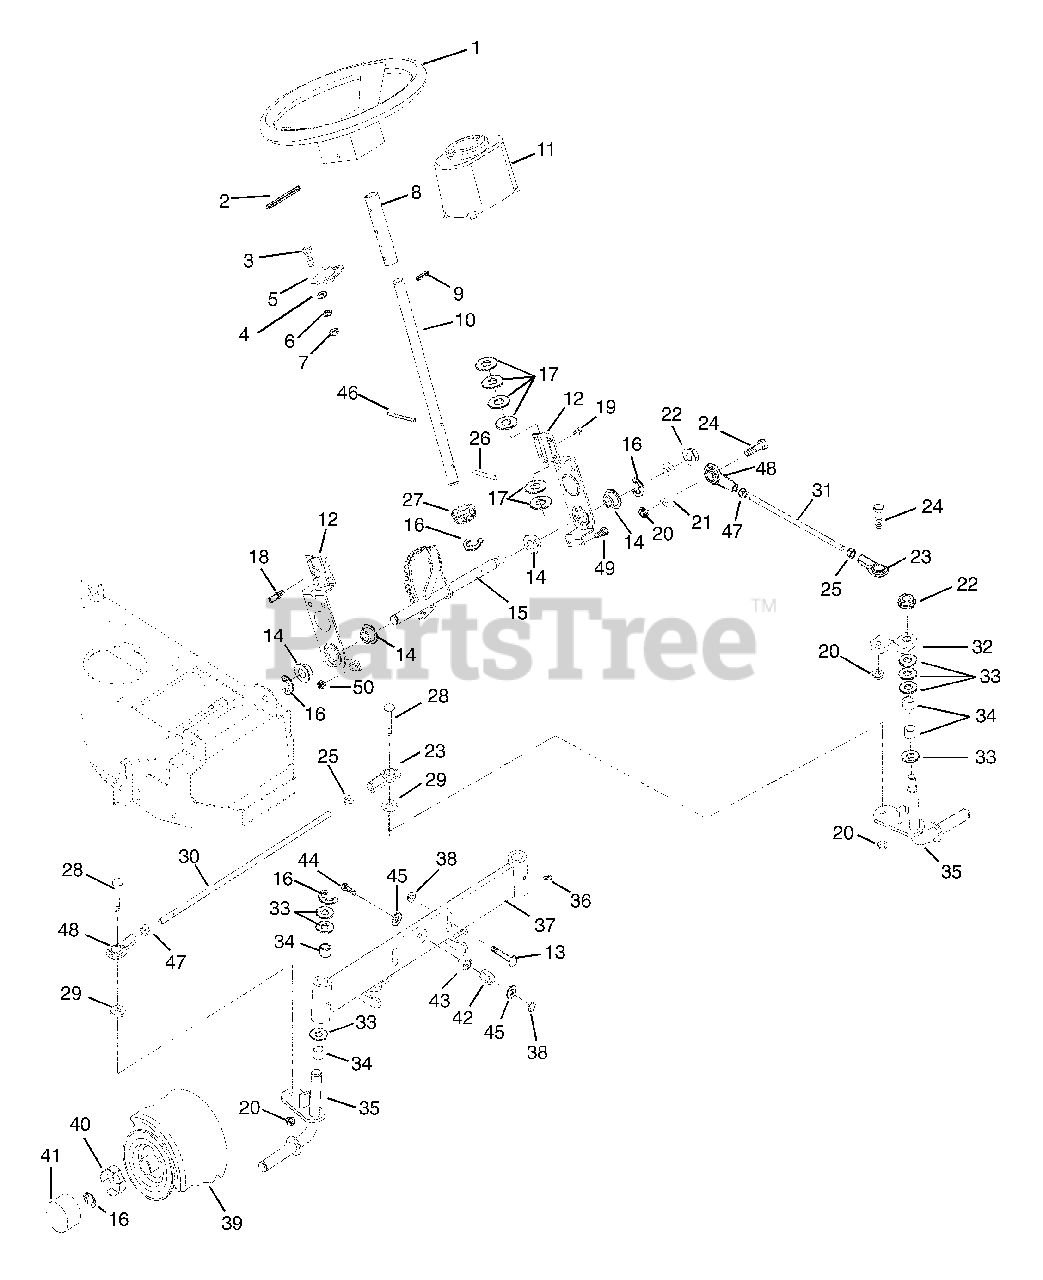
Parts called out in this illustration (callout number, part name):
1	STEERING WHEEL 13"
2	PIN-ROLL .250X1.75
3	@BLT-HEX .31-18X.75 GR5 YWZC
4	@WSHR-FL-STL.312X.734X.065 YWZ
5	BRG-FLG .751X2 HOLESX.81
6	WSHR-LK .312X.097 HVY YWZC
7	@NUT-HEX .31-18 YWZC
8	TUBE .754 X .999 X 5.00
9	PIN-ROLL .250X1.000
10	COLUMN, STEERING
11	CONE- STEERING COLUMN
12	BRACKET, STEERING GEAR
13	@BLT-HEX .38-16X1.50 GR5 YWZC
14	BSHG-FLG .750X1.093X.625X1.375
15	GEAR, STEERING
16	RG-RTNG-EXT .750X.050
17	WSHR-FL-STL.755X1.375X.062YWZC
18	FTG-LUBE .25-28X.256 YWZC
19	@SCR-TAP .25-20X.37 HWH YWZ TR
20	@NUT-LK-CTR .38-16 YWZC
21	ARM, STEERING ROD
22	NUT-LK .563-18 GR5 YWZC
23	ROD END, .38 RH
24	BLT-BTHD .38-16X1.25 GR5
25	NUT-JAM .375-24 YWZC
26	PIN .249X1.125 DRIV-LOK SP
27	PINION GEAR-STEERING
28	@BLT-HEX .38-16X1.75 GR5 YWZC
29	BSHG-SLV .377X.624X.370
30	ROD - TIE
31	LINK - DRAG
32	ARM - STEERING SPINDLE
33	WSHR-FL-STL.755X1.375X.062YWZC
34	BSHG-SLV .750X.814X .750 BRZ
35	SPINDLE - LH
35	SPINDLE - RH
36	FTG-LUBE .25-28X.256 YWZC
37	AXLE, FRONT
38	@NUT-LK-CTR .38-16 YWZC
39	TIRE/WHEEL ASSY 15 X6.00-2 PLY
39	WHEEL W/BEARINGS
39	BSHG .75 BORE
39	FTG- LUBE .25-28X.97
39	BRG-BALL .752X1.380X.500
40	SPINDLE CUP
41	HUB CAP
42	BSHG-SLV .377X.623X.775 HEX
43	BSHG-SLV .626X1.000X.524 HEX
44	@BLT-HEX .38-16X1.75 GR5 YWZC
45	WSHR-FL-STL .380X1.50X.125YWZC
46	PIN-ROLL .188X1.13
47	NUT-JAM .375-24 LH YWZC
48	END, ROD-.38 LH
49	@BLT-HEX .25-20X.75 GR5 YWZC
50	@NUT-LK-CTR .25-20 YWZC
